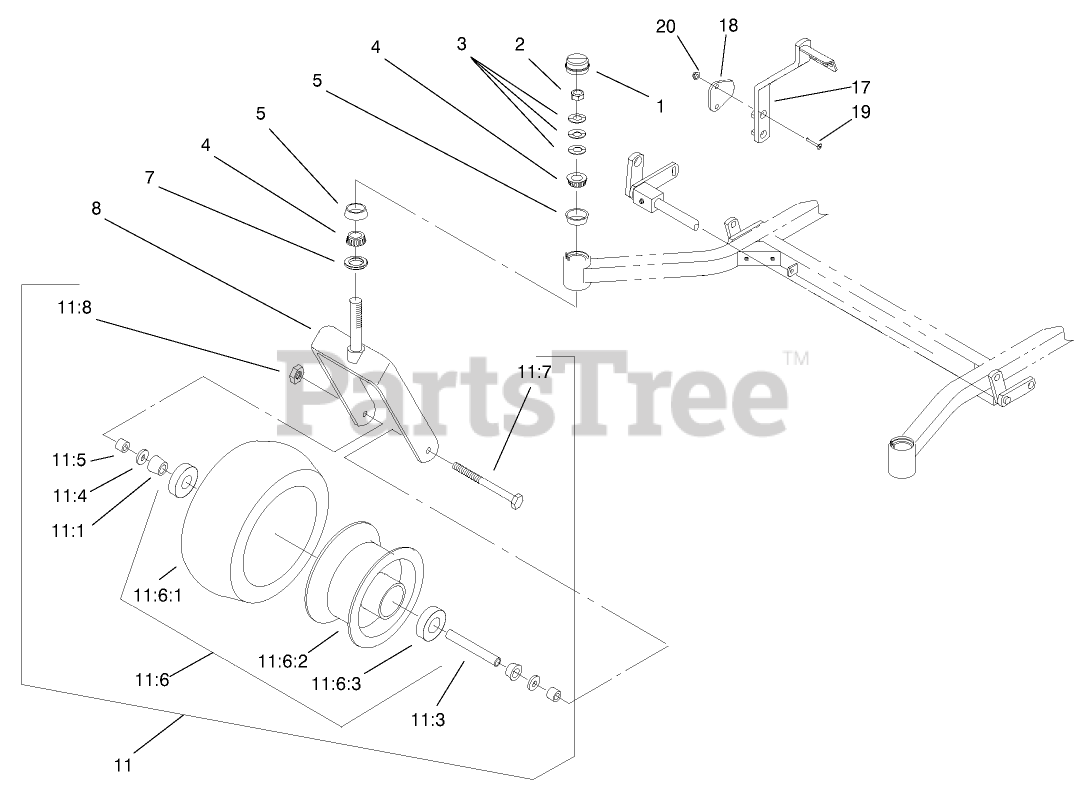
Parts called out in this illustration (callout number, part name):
1	Cap-Grease
2	LOCKNUT
3	Washer-Bellevue
4	BEARING-CONE, TAPERED
5	BEARING-CUP, TAPERED
7	Seal-Grease
8	Caster
11	Caster Wheel ASM
11:1	BEARING-CONE
11:3	Spacer-Front Caster
11:4	Seal-Bearing
11:5	Spacer-Bearing
11:6	Wheel & Tire ASM
11:6:1	Tire
11:6:2	Wheel
11:6:3	BEARING-ROLLER, CUP
11:7	SCREW-HH
11:8	NUT-LOCK, NI
17	LEVER-LIFT, DECK
18	Strap
19	SCREW
20	NUT-HF
